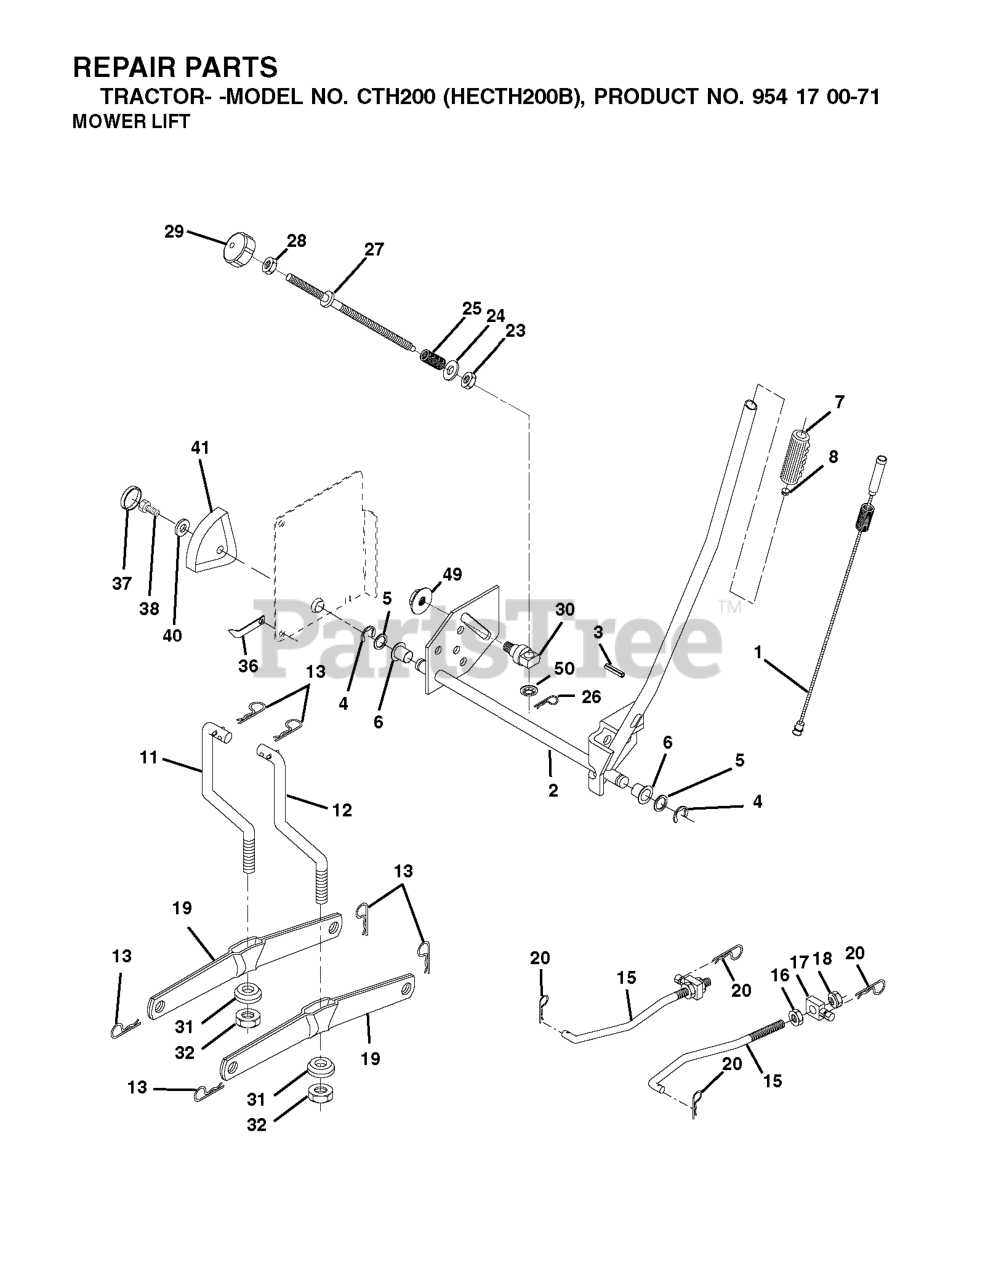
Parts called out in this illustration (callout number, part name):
1	WIRE ASM INNER W/ PLUNGER LT
2	SHAFT ASM R HANDLE
3	PIN GROOVE.
4	RETAINING RING LT
6	BEARING.NYLON
7	GRIP HANDLE
8	PLUNGER BUT KIT
11	LINK
12	LINK
13	RETAINER-SPRNG RB
15	LINK.SUSPENSION.FRONT
16	NUT.HEX.JAM.1/2-13
18	NUT.LK.W/WSH.1/2.
19	ARM.REAR.SUSPENSION
20	SPRING RETAINER
25	SPRING**
26	RETAINER CLIP
27	ROD ADJ LIFT
28	NUT
29	KNOB INF 3/8-16
31	BEARING.PIVOT.LIFT
32	NUT CROWNLOCK 3/8-24
36	POINTER, HEIGHT INDICATOR(2 2)
38	SCREW 5/16-18X1
41	HEIGHT INDICATOR
49	NUT
50	NUT PUSH M
